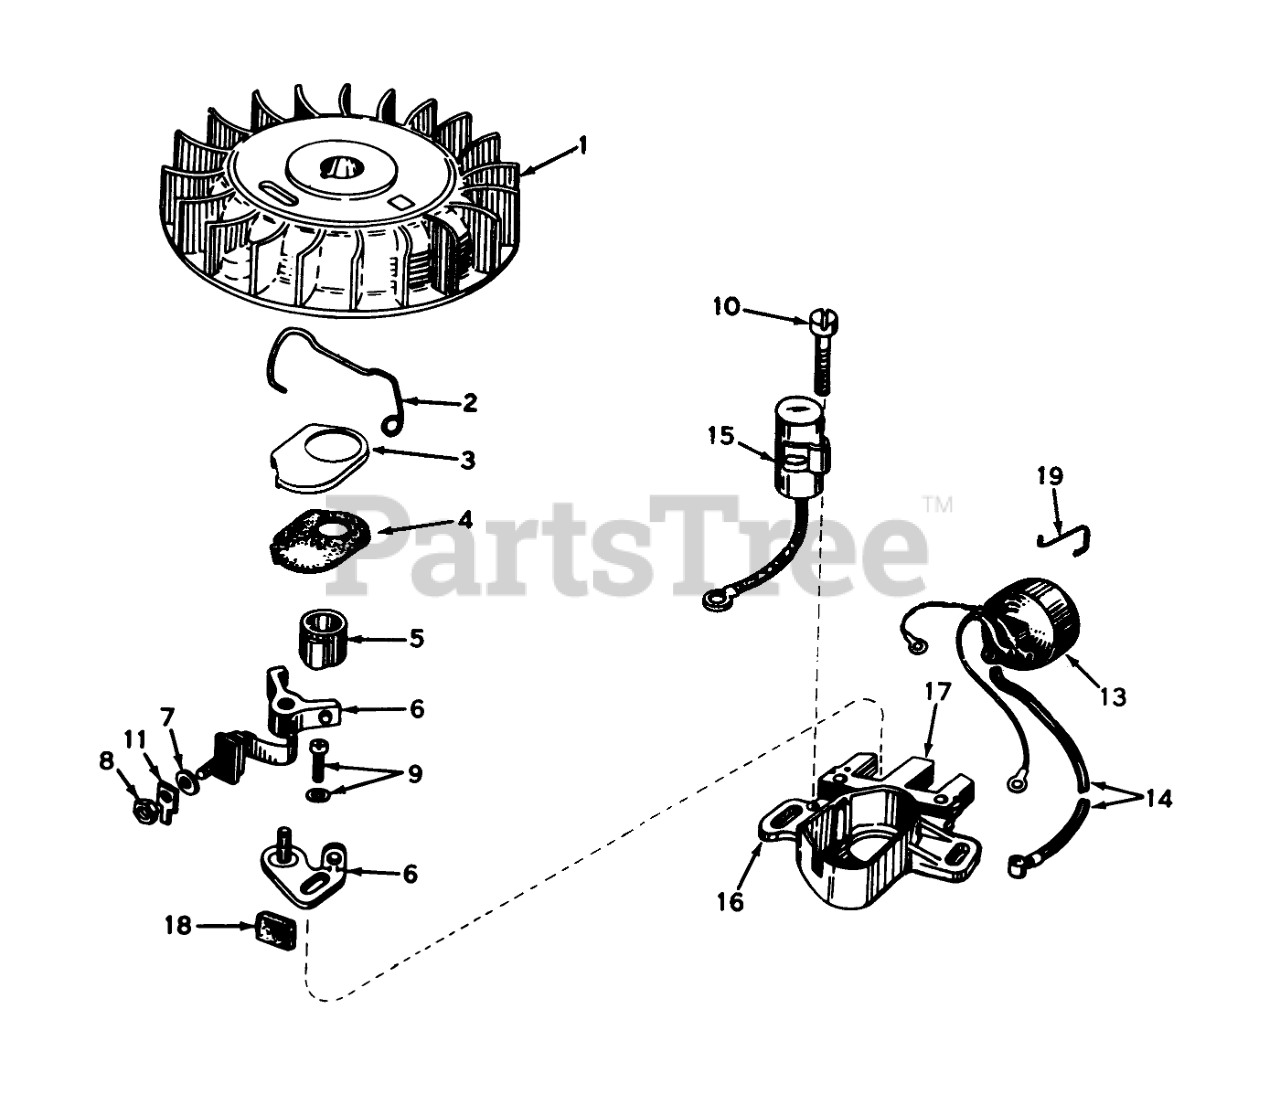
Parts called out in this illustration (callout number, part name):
1	Flywheel (Incl. Nos. 3 & 4)
2	Spring Breaker Box
3	Cover-Dust
4	Gasket, Dust Cover
5	Cam, Breaker
6	Breaker Assy.
7	Washer
8	DECAL
9	Breaker Screw
10	Condenser Screw
11	Terminal, Ground
13	Coil Assembly (Incl. No. 14)
14	Wire, Lead
15	Condenser
16	Core & Plate
17	Stator Assembly (Incl. Nos. 2, 3, 4, 6thru 11, 13, 15, 16, 18 & 19)
18	Felt,Cam Wiper
19	Clip, Coil
